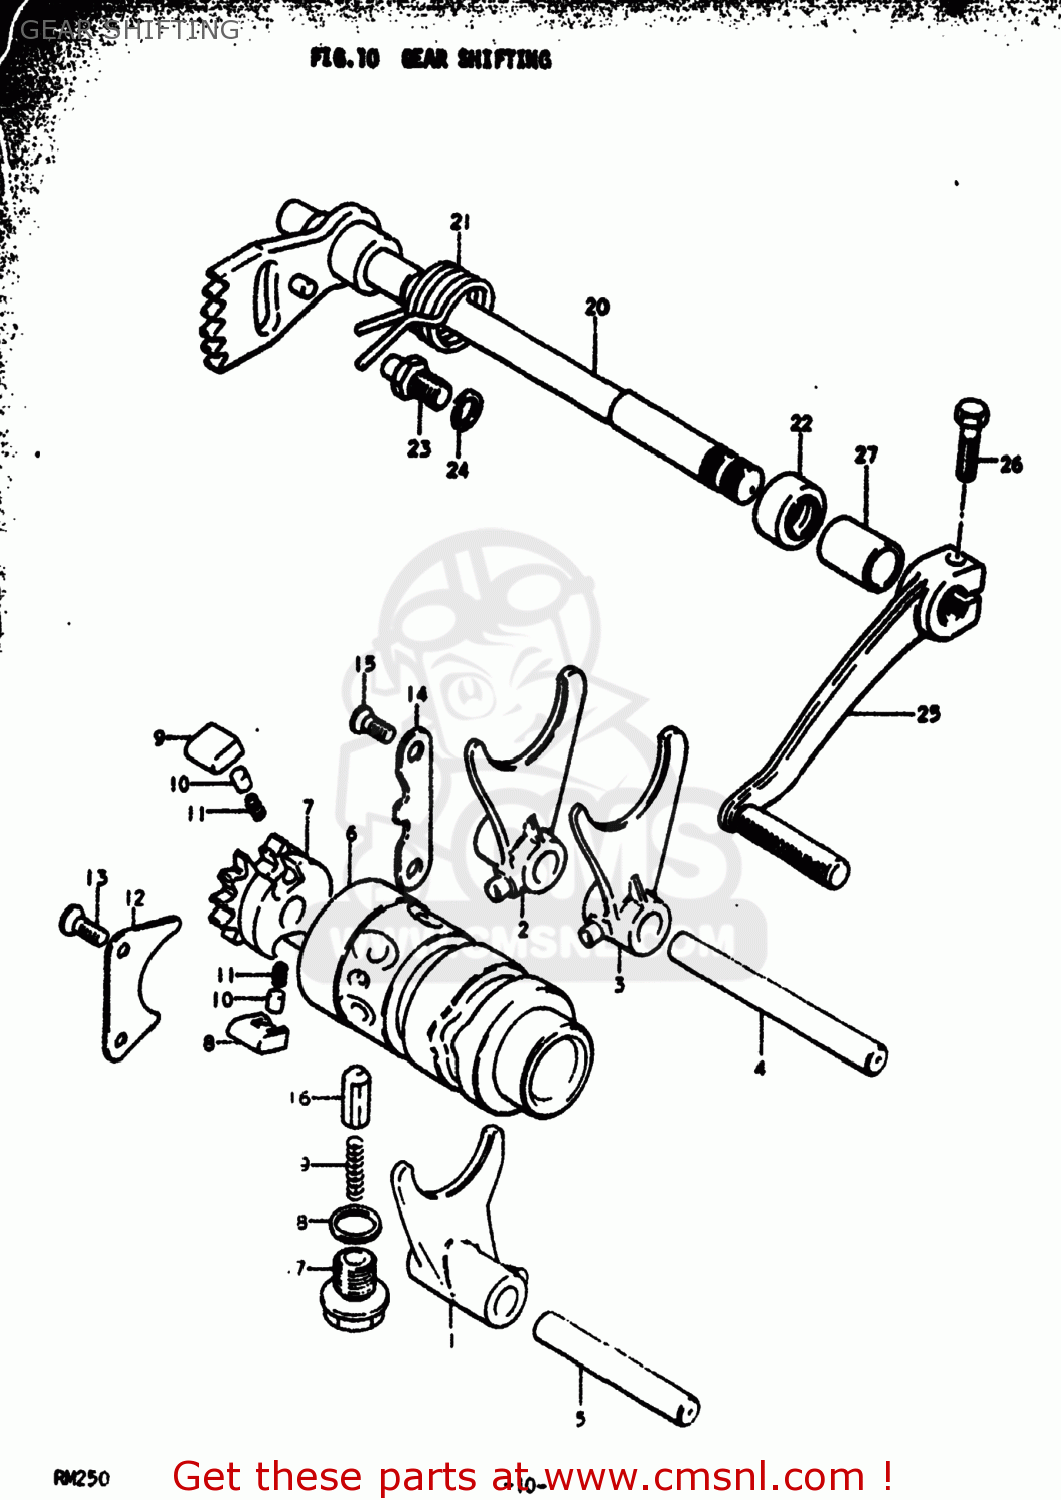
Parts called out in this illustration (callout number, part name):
1	FORK,GEAR SHIFT NO.1
2	FORK,GEAR SHIFT NO.2
3	FORK,GEAR SHIFT NO.3
4	SHAFT,GEAR SHIFT FORK
5	SHAFT,GEAR SHIFT FORK
6	CAM,GEAR SHIFT
7	RETAINER,GEAR SHIFT CAM
8	PAWL,GEAR SHIFT NO.1
9	PAWL,GEAR SHIFT NO.2
10	PIN(5X8)
11	SPRING
12	LIFTER,GEAR SHIFT PAWL
13	SCREW
14	STOPPER,GEAR SHIFT POLE
15	SCREW
16	STOPPER,GEAR SHIFTING
17	BOLT,GEAR SHAFT CAM STOPPER
18	GASKET(14X19.2X2) (NAS)
19	SPRING
20	SHAFT,GEAR SHIFT
21	SPRING
22	OIL SEAL
23	STOPPER,GEAR SHIFT CAM
24	LOCK WASHER
25	LEVER ASSEMBLY,GEAR SHIFTING
26	BOLT
27	CUSHION
